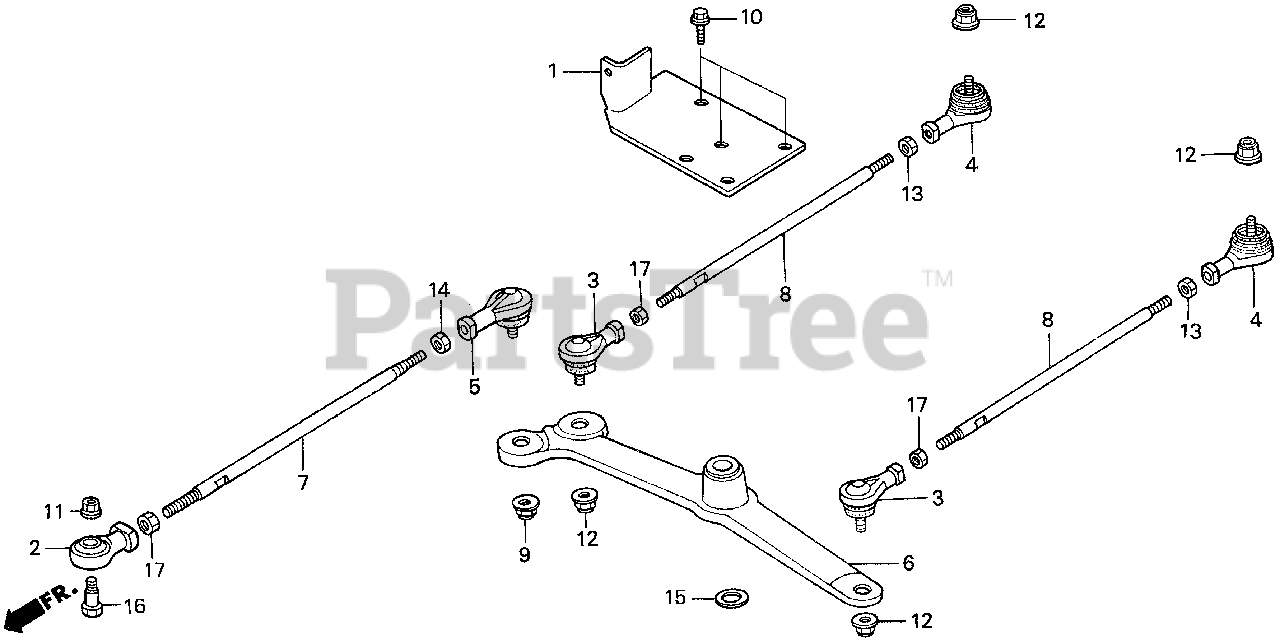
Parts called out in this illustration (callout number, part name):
1	BRACKET B, FUEL TANK
2	EYE, STEERING ROD END
3	JOINT, R. BALL (ER12)
4	JOINT, L. BALL (ER12)
5	JOINT, L. BALL (ER10)
6	ARM, RR. STEERING
7	ROD, RR. STEERING RELAY
8	TIE ROD, RR.
9	NUT, SELF-LOCK (10MM)
10	BOLT, FLANGE (8X20)
11	NUT, FLANGE (12MM)
12	NUT, SELF-LOCK (12MM) (SATO RASHI)
13	NUT, L. HEX. (12MM)
14	NUT, L. HEX. (10MM)
15	WASHER, THRUST (17MM)
16	PIN, ROD END
17	NUT, HEX. (12MM)
